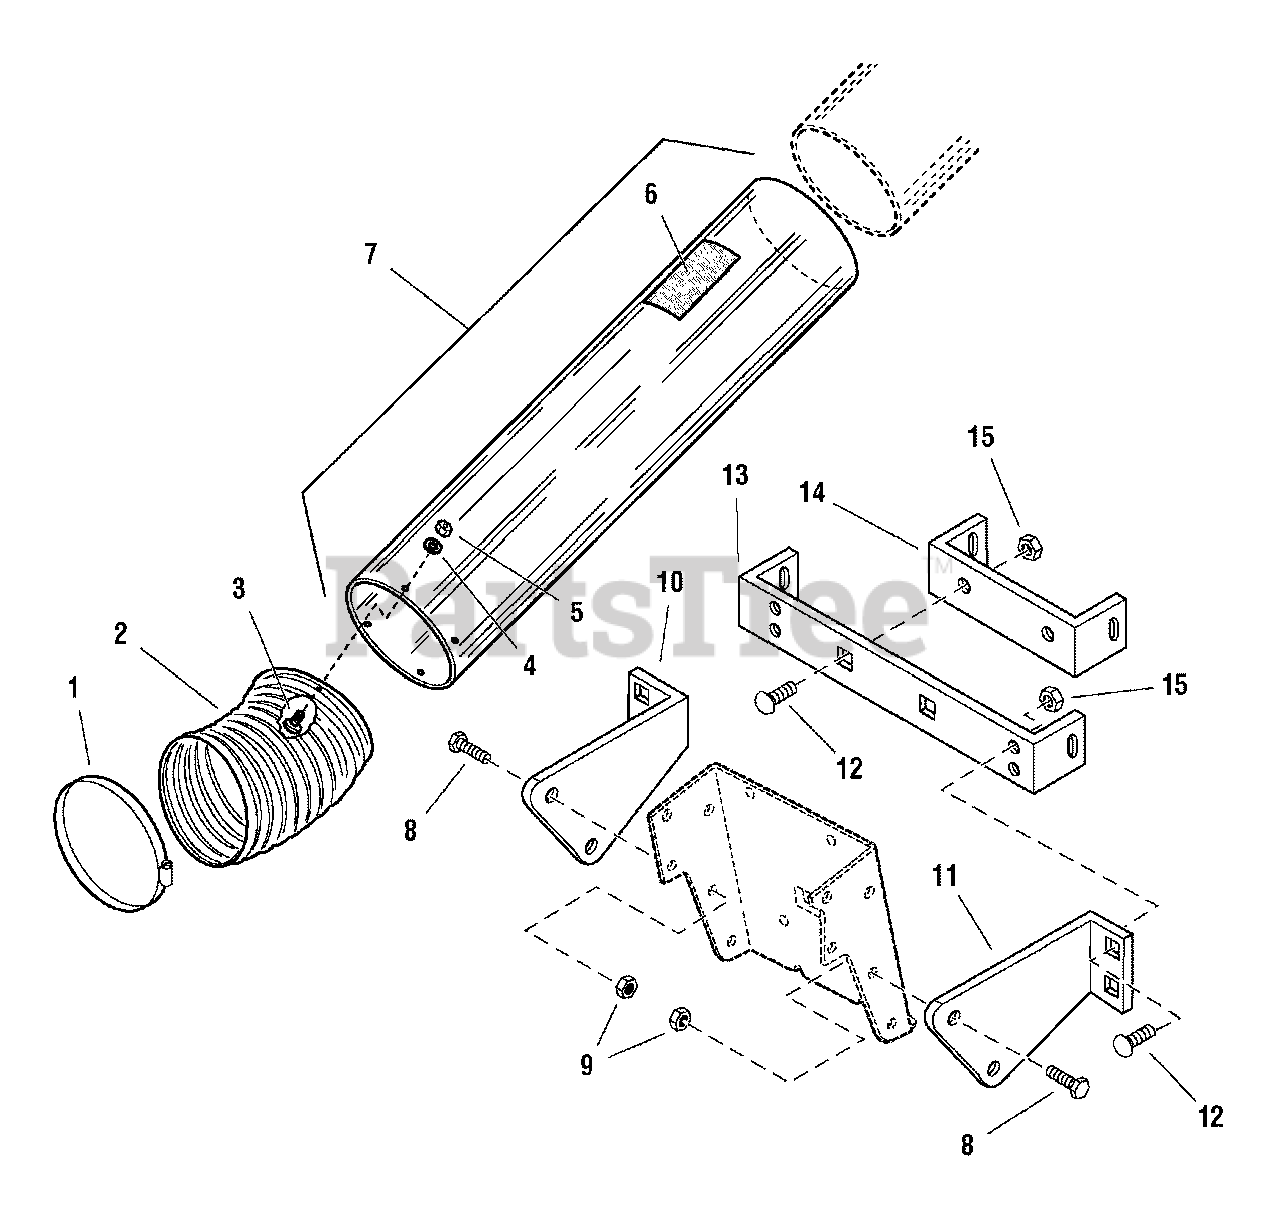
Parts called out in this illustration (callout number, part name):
1	CLAMP, Hose 6", Band Type
2	HOSE, Vac Col, 6 x 12
3	SCREW, Truss Head Phillips, #10-32 x 1/2
4	WASHER, #10-32
5	NUT, Hex Washer Assembly, #10-32
6	DECAL, Cleaning Instructions
7	TUBE & DECAL ASSEMBLY (Includes Ref. No. 6)
8	CAPSCREW, Hex Head, 3/8-16 x 1
9	NUT, Hex Centerlock, 3/8-16
10	BRACKET, LH
11	BRACKET, RH
12	CARRIAGE BOLT, 3/8-16 x 1-1/4
13	CROSS BAR
14	HITCH, Inner
15	NUT, Nylock, 3/18-16
